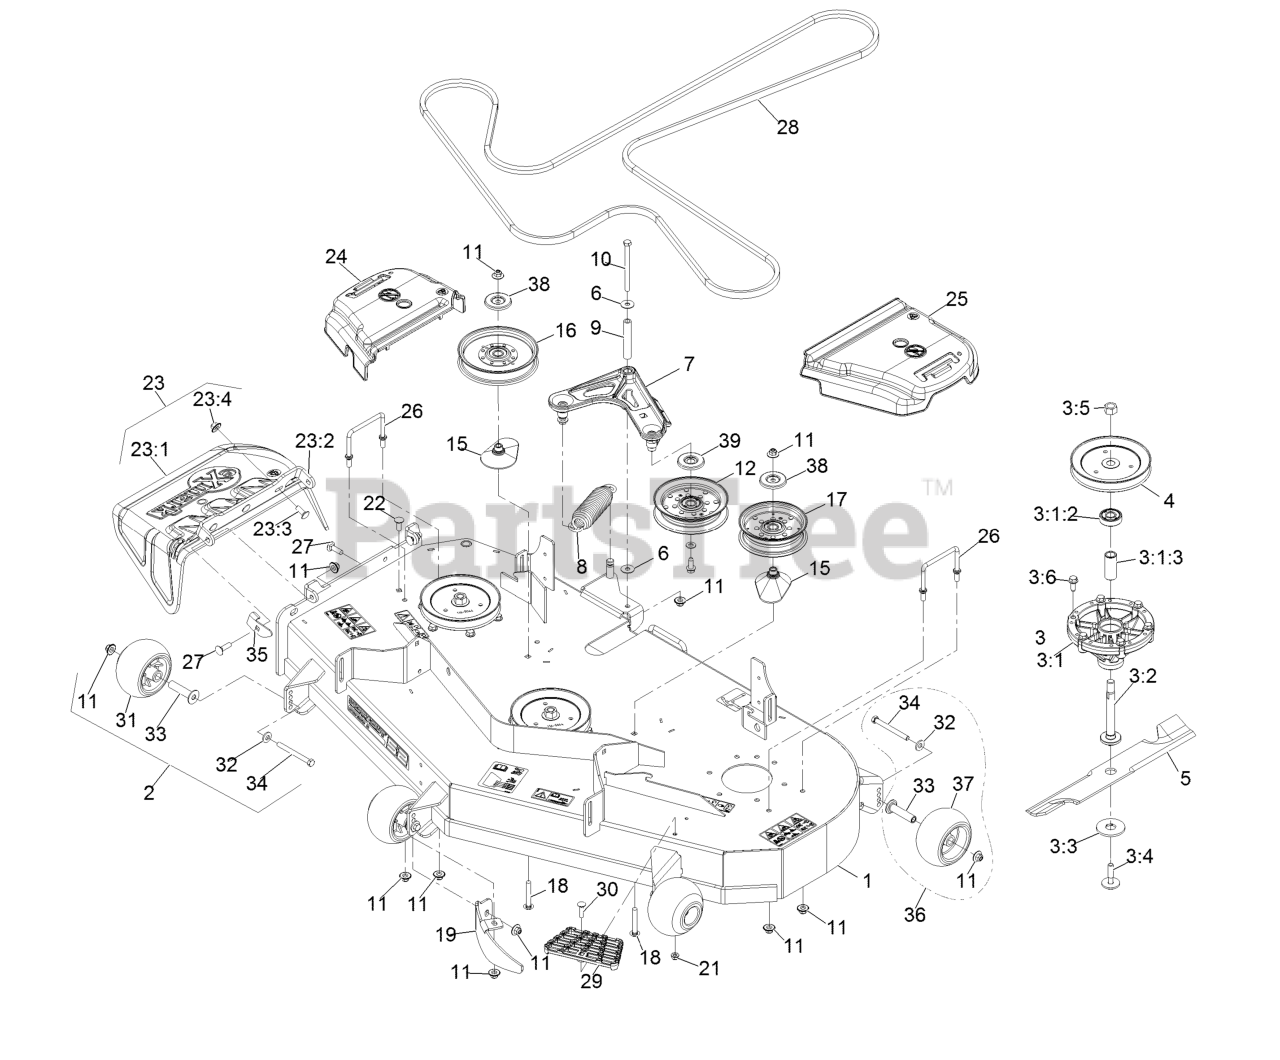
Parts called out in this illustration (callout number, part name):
1	ASM-Deck W/Decals 523
2	Kit, Anti-Scalp Roller
3	ASM, Cutter Housing Complete
3:1	ASM-Cutter Housing
3:1:2	Bearing
3:1:3	Spacer-Bearing
3:2	Spindle-Hex Pilot
3:3	Washer-Hex Blade Drive
3:4	Bolt-Blade, Sem
3:5	Nut-Hex
3:6	Screw-Forming, Thread
4	Sheave,Blade Drive 6.50
5	Blade, Solid
5	Blade, Low Lift
5	Blade, Mulching
5	Blade-Notched
5	Blade-Extreme 2, 18.00"
7	Idler Arm ASM
8	Spring-Extension
9	Bushing
10	Screw-HH
11	Nut-Flange, NI
12	Idler-Pulley, Flat
15	Spacer-Pulley
16	Idler-Pulley, Flat 6.00X1.00
17	Idler-Pulley, Flat 5.00X1.31
18	Screw-CARR
19	Baffle-Dogleg, Lze-Pns-52
21	Nut-HF, NI
22	Screw-CARR
23	ASM,Discharge Chute
23:1	Chute, Discharge
23:2	Bracket,Discharge Chute
23:3	Screw-CARR
23:4	Nut-Flange, NI
24	Cover-Belt, RH
25	Cover-Belt, LH
26	Wireform-Cover
27	Bolt-CARR
28	Belt-V
29	Step-Deck
30	Screw-CARR
31	Roller-Anti-Scalp
32	Washer-Belleville
33	Axle, Roller
34	Screw-HH
35	Stop-Discharge Chute
36	Kit-Antiscalp Roller
37	Roller-Scalp, Anti
38	Shield-Dust
39	Shield-Guard, Dust
